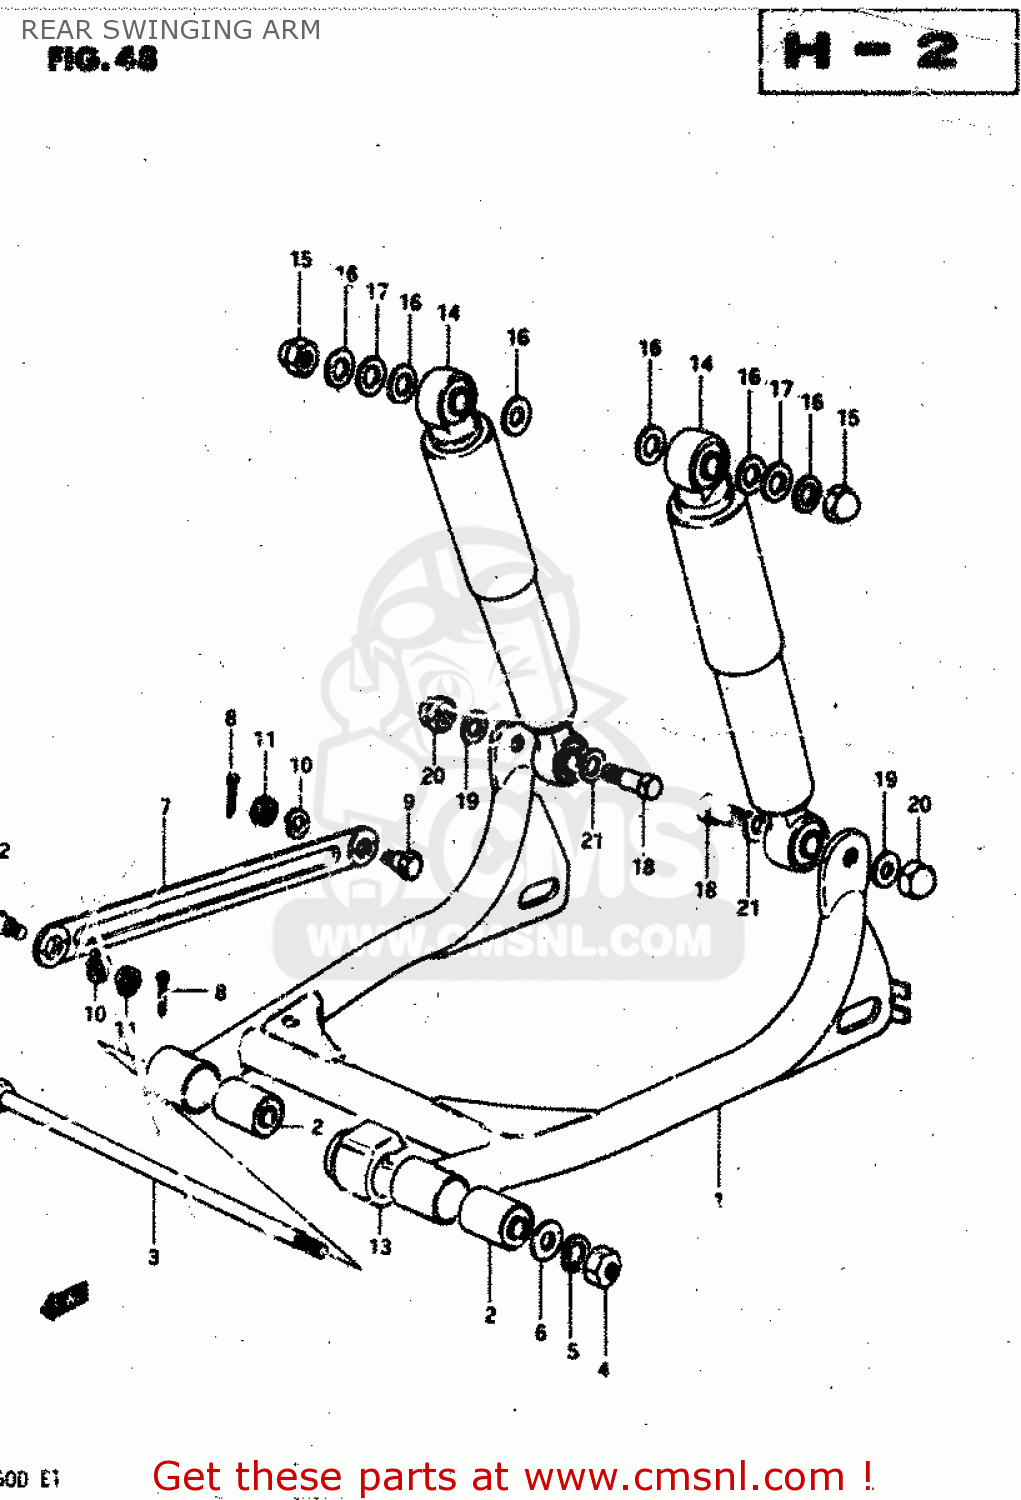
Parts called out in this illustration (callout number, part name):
1	REAR SWINGING ARM SET
2	BUSHING(10X23X35)
3	SHAFT,REAR SWING ARM
4	NUT
5	LOCK WASHER
6	WASHER
7	LINK,RR BRAKE TORQUE
8	PIN
9	BOLT(8X26.5)
10	LOCK WASHER
11	NUT
12	BOLT(8X22.5)
13	BUFFER,CHAIN TOUCH DEFENSE
14	SHOCK ABSORBER ASSY
15	NUT, LOWER LH
16	WASHER
17	WASHER(10.5X24X3.2)
18	BOLT
19	WASHER
20	NUT, LOWER LH
21	WASHER
